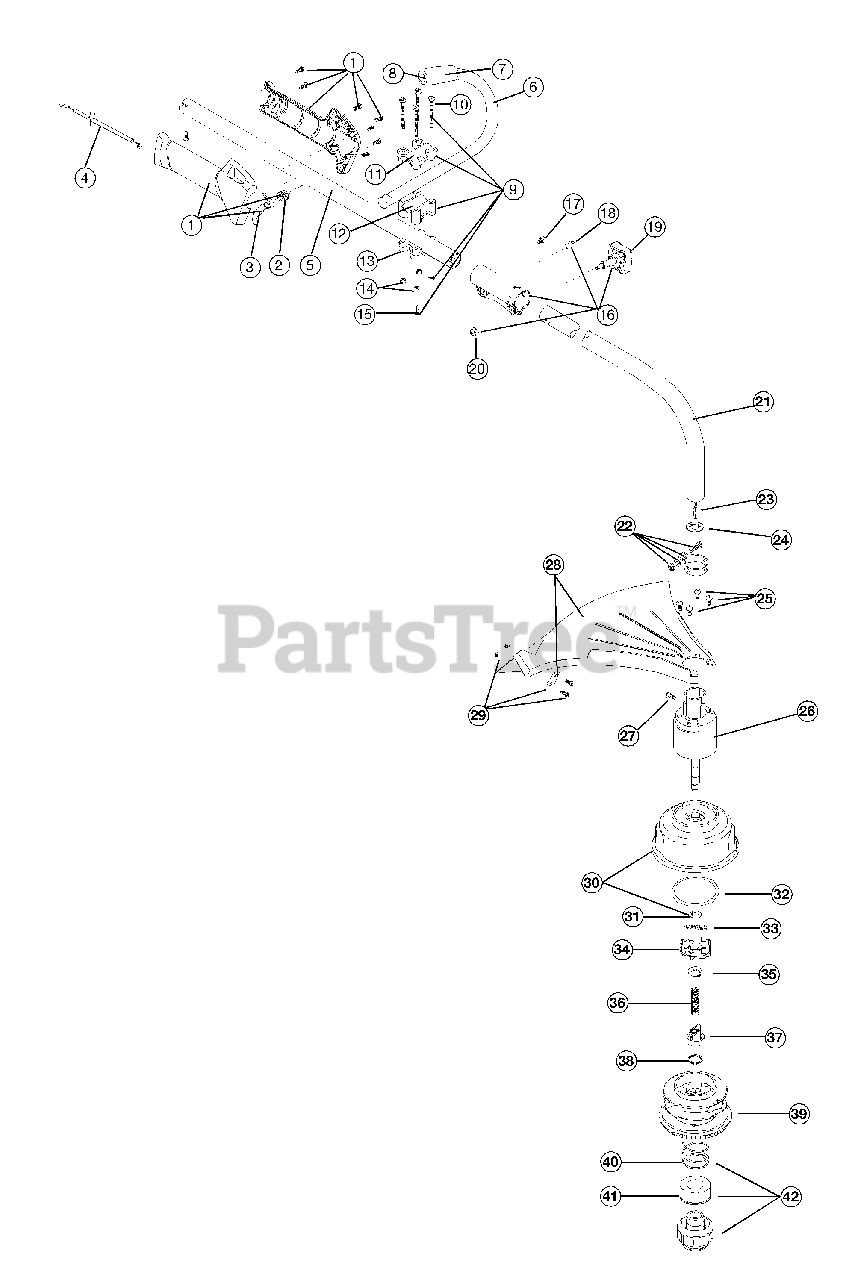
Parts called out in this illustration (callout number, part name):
1	Throttle Housing and Trigger Assembly
2	Throttle Trigger Spring
3	Throttle Trigger
4	Throttle Cable Assembly
5	Upper Drive Shaft Housing Assembly
6	J-Handle Assembly
8	Tube Closure
9	Handle Bracket Assembly
11	Upper Handle Clamp
12	Middle Handle Clamp
13	Lower Handle Clamp
15	Anti-Rotation Screw
16	Click-Link Coupler
19	Adjustment Knob
20	Knob Retaining Nut
21	Lower Drive Shaft Housing Assembly
22	Lower Clamp Assembly
23	Lower Flexible Drive Shaft
24	Palnut
25	Shield Mounting Screw
26	Bushing Housing Assembly
27	Anti-Rotation Screw
28	Shield and Blade Assembly
29	Blade Assembly
30	Outer Spool Assembly
31	Retainer
32	Thrust Washer
33	Small Spring
34	Slider
37	Plunger
39	Inner Reel
40	Large Spring
41	Foam Seal
42	Bump Head Knob Assembly
